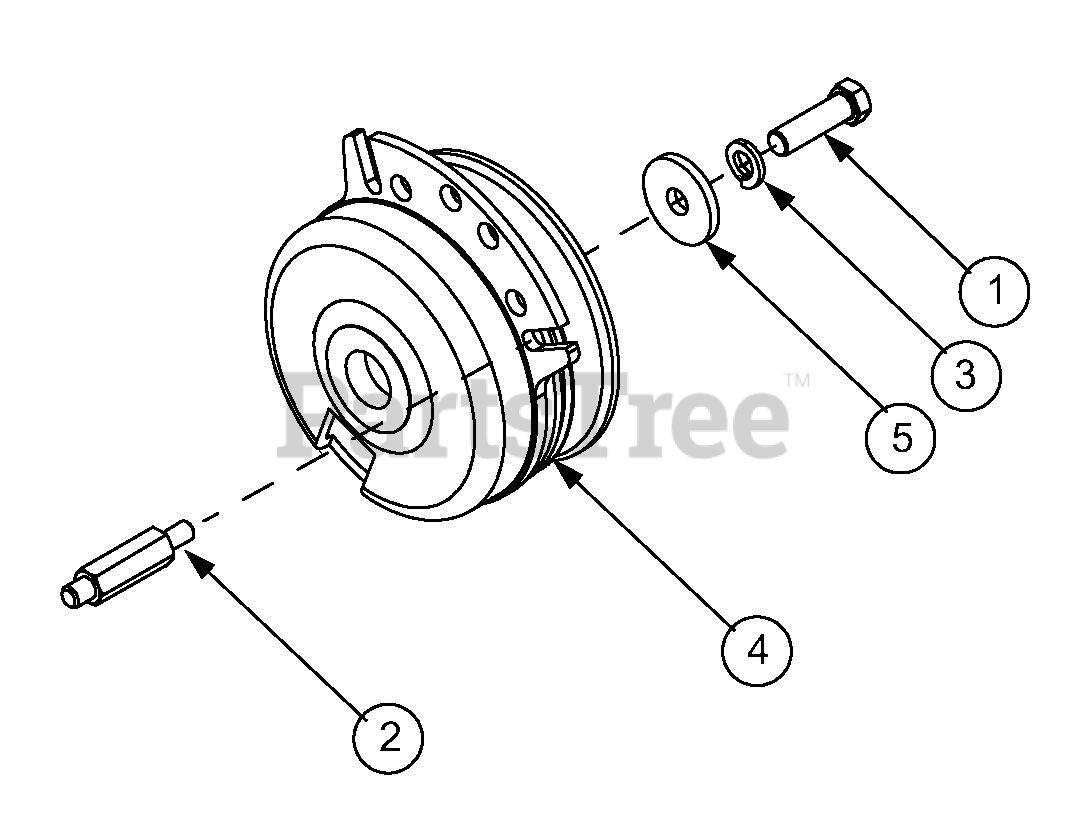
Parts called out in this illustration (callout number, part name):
1	Screw, Hex Cap, 7/16-20 x 1.5 GR5
2	Stud, Clutch Stop
3	Washer, Lock, 3/8
4	Clutch Assy, PTO
5	Washer, Flat, .445 x 1.5 x 1.72 Hdn
